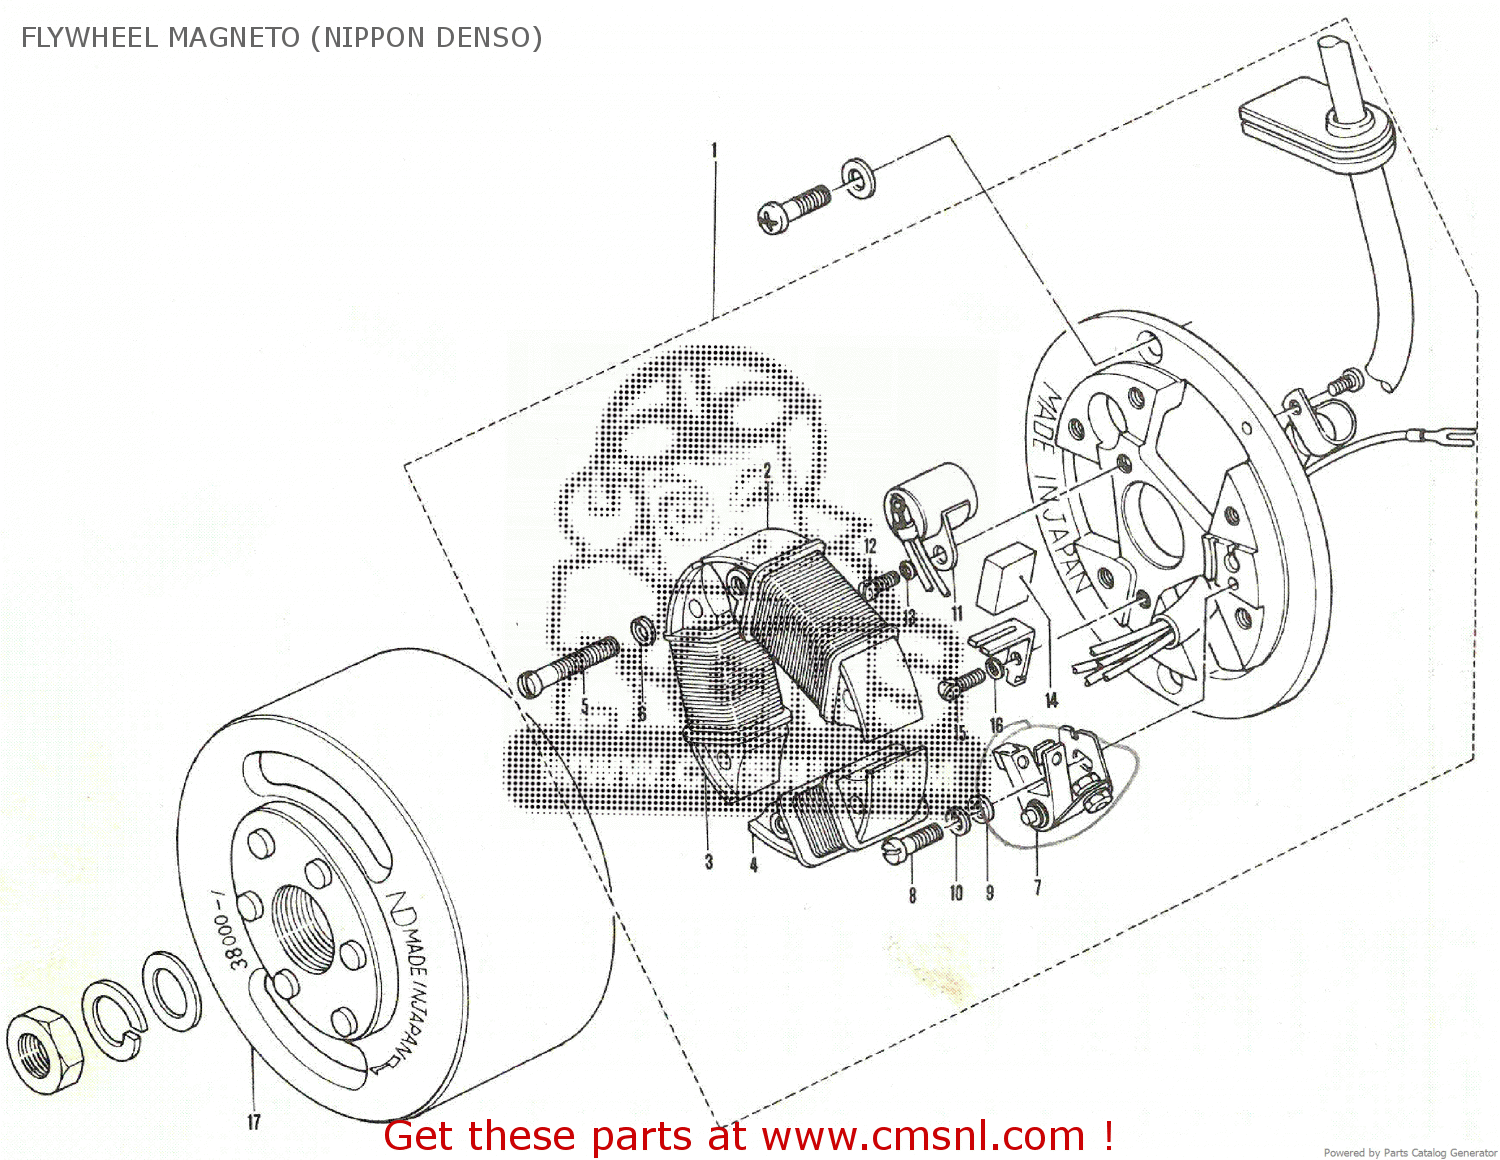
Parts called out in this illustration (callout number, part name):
1	STATOR ASSEMBLY
2	COIL,LIGHTING
3	COIL,LIGHTING
4	COIL
5	SCREW
6	LOCK WASHER
7	POINT ASSEMBLY,CONTACT
8	.SCREW
9	WASHER
10	LOCK WASHER
11	CONDENSER
12	CROSS HEAD SCREW
13	LOCK WASHER
14	FELT,OIL
15	SCREW
16	LOCK WASHER
17	ROTOR ASSEMBLY
